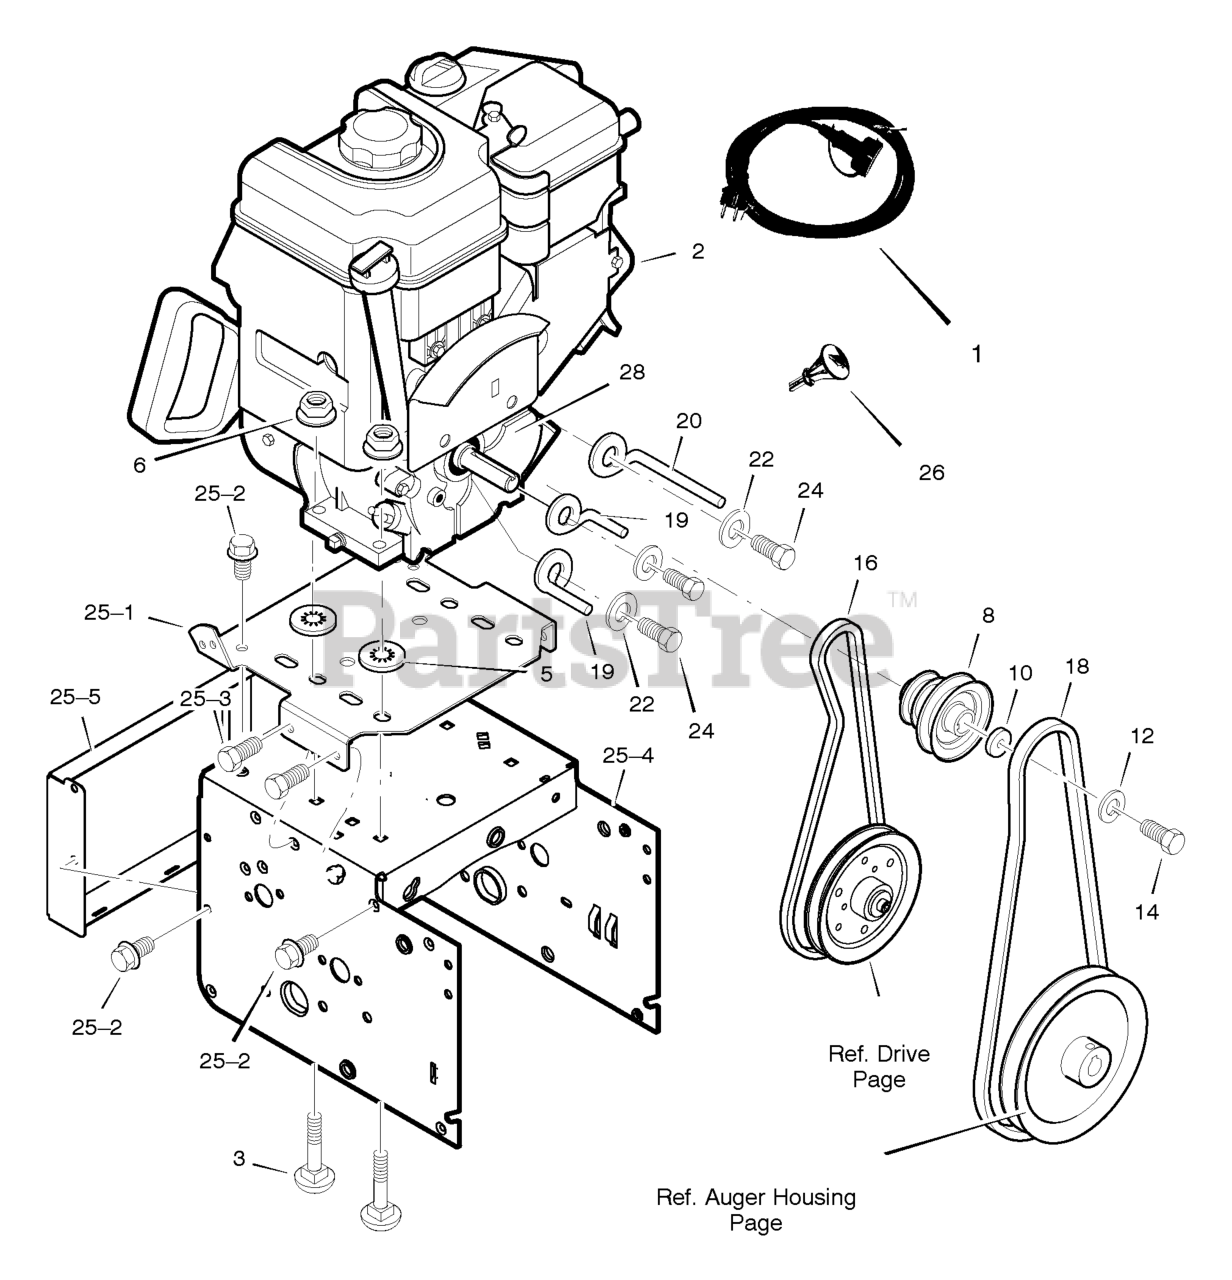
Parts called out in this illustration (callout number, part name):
1	CORD, STARTER
2	ENGINE
3	BOLT, CARRIAGE 5/16-18
5	RETAINER, PUSH
6	NUT, HEX 5/16-18
8	PULLEY, ENGINE
10	WASHER
12	WASHER .38ID
14	SCREW, 3/8-24 x 1.00
16	BELT, HYDRO DRIVE
18	BELT, AUGER V 4L
19	GUIDE, BELT
20	GUIDE, BELT
22	WASHER, SPTLK .31X.58X.08
24	SCREW, 5/16-24 x 0.75
25	FRAME ASSEMBLY
25-1	PLATE, ENGINE MOUNT
25-2	SCREW, TAP 1/4-20 X .63
25-3	SCREW, TAP 5/16-18 X .50
25-4	FRAME, MOTOR BOX
25-5	PANEL, BACK - HYDRO
26	KEY, ENGINE
28	BRACKET, SHIELD
